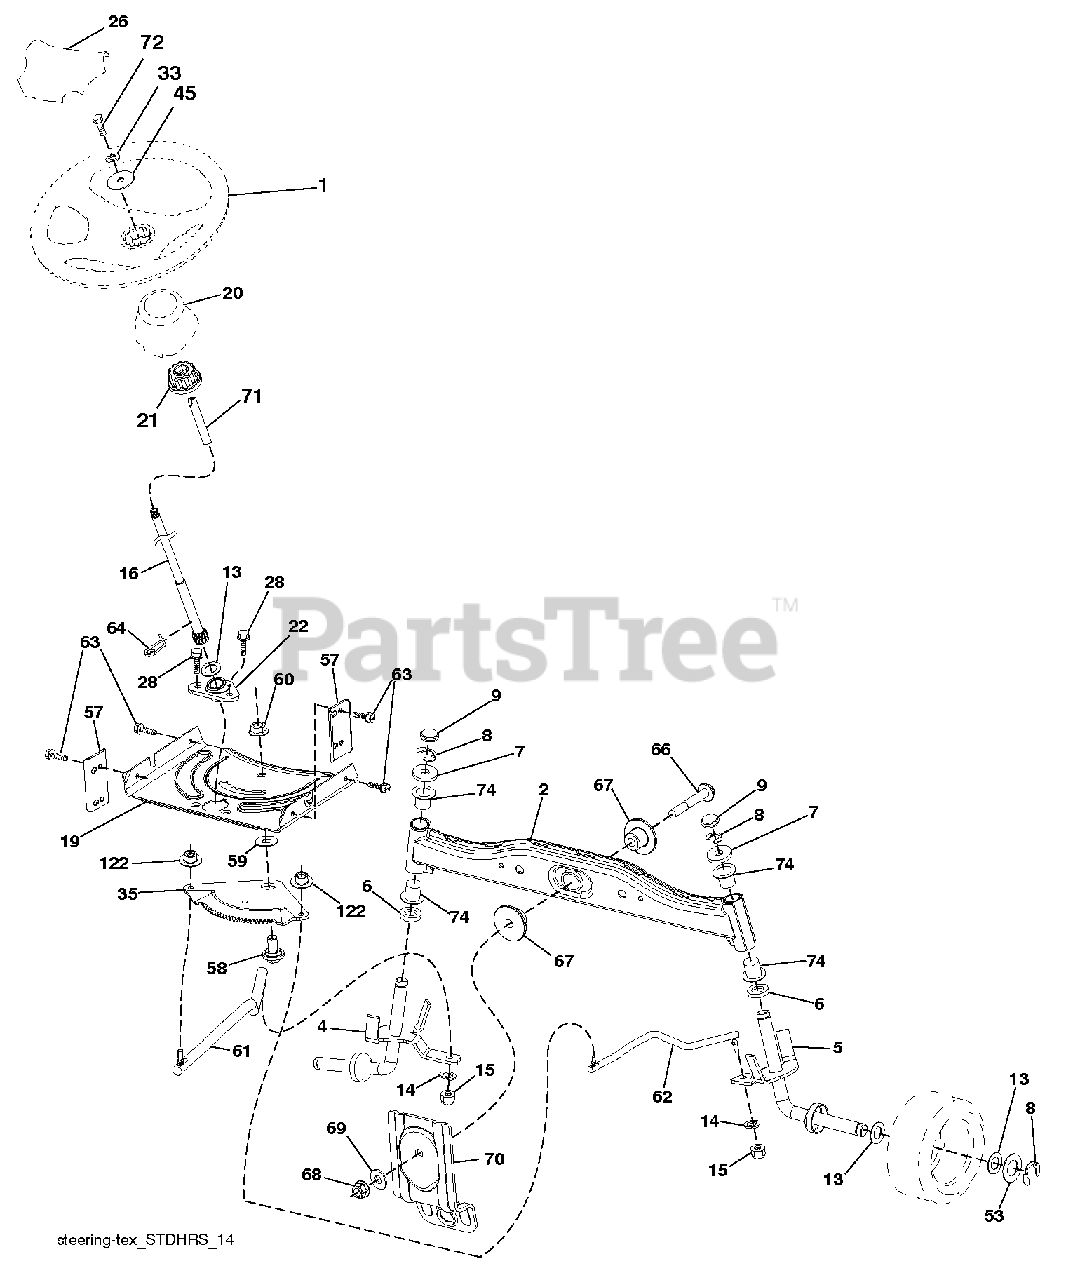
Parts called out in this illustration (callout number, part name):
1	WHEEL.STEERING.STDSRR.BLK/OV
2	AXLE HALF ASM-WELDED
4	SPINDLE.WELDED.LH.15"TEX
5	SPINDLE.WELDED.RH.15"T
8	RING CLIP
9	CAP.SPINDLE
14	WASHER, LOCK 3/8
15	NUT CROWNLOCK 3/8-24
16	SHAFT.STEER.3/4.PLATED.TEX
19	PLATE.STEER.DDL.NLT/NG
20	BOOT.STEERING.PREDATOR.LT.BLAC
21	ADAPTER, WHEEL STNG..
22	STEERING.SUPT.LOWER.
26	CAP.WHL.STRNG.STDSRRD.SRS.BLK
28	SCREW, 3/8-16X3/4
33	LOCKWASHER
35	GEAR.SECTOR.PLATE.DDL.
45	WASHER.11/32
53	WASHER.HARDENED
57	BRACKET.UPSTOP.TEX
58	BOLT.SHOULDER.SECTOR.P
59	WASHER.THURST.SECTOR.S
60	NUT FLANGE LOCK 5/8-11
61	DRAGLINK.LH.BALLSTUD.D
62	DRAGLINK.RH.BALLSTUD.D
63	SCREW
64	RETAINER.CLIP.SPRING.S
66	BOLT HEX FGHD 7/16-14 X 3 SERR
67	BUSHING.PM.FRONT AXLE
68	NUT.LOCK.FLANGE.7/16
69	WASHER.1.5X.505X.118
70	BRKT.DECK.SUSPENSION.F
71	SHAFT.EXTEN.STRG.SPLINE
72	BOLT 5/16-18 X 4 W/PATCH
74	BRNG T
